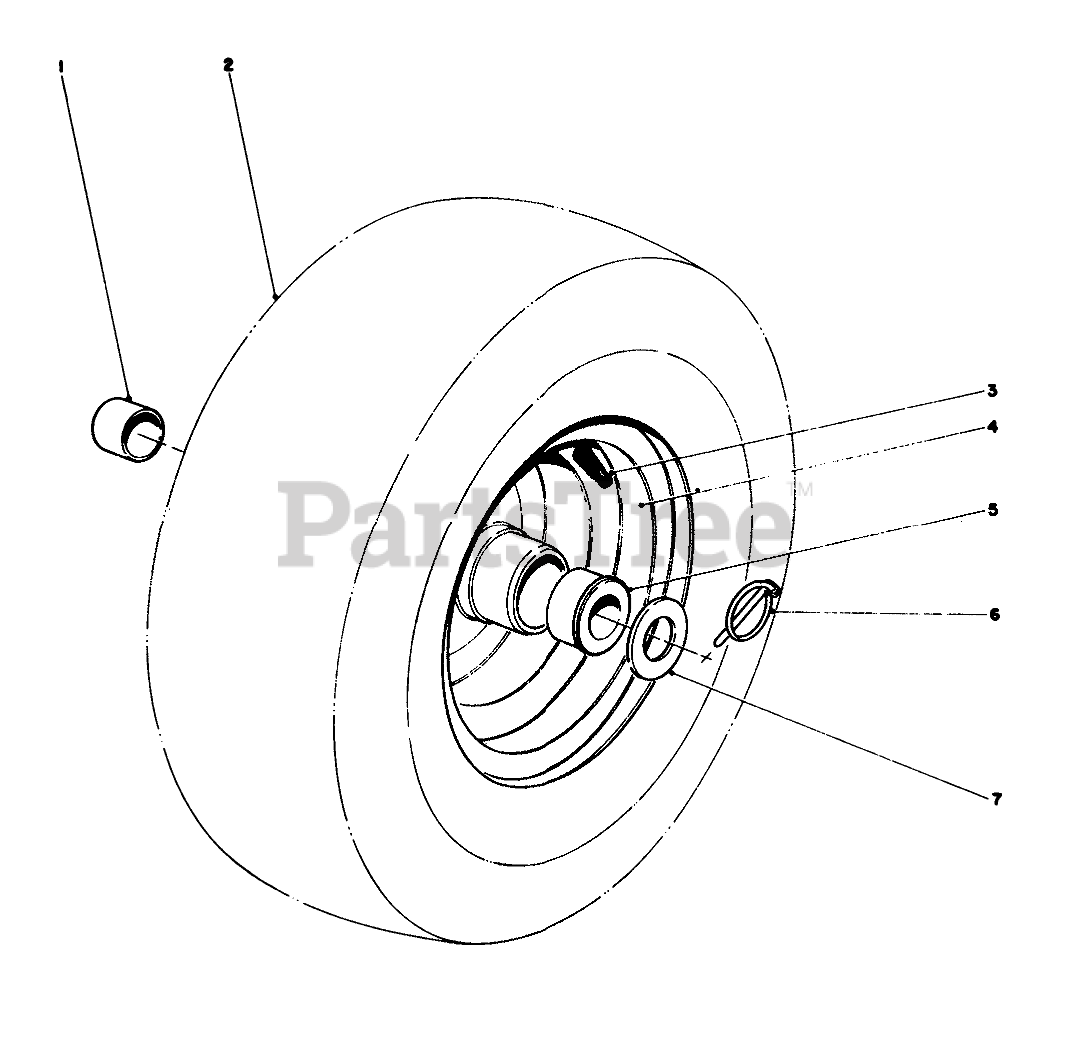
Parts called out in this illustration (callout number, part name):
1	.877ID X .750LG BSHG
2	Tire
3	STEM-VALVE
4	Wheel & Hub Assembly (Incl. Ref. #1 & 5)
5	BUSHING
6	PIN-LYNCH
7	WASHER-THRUST
